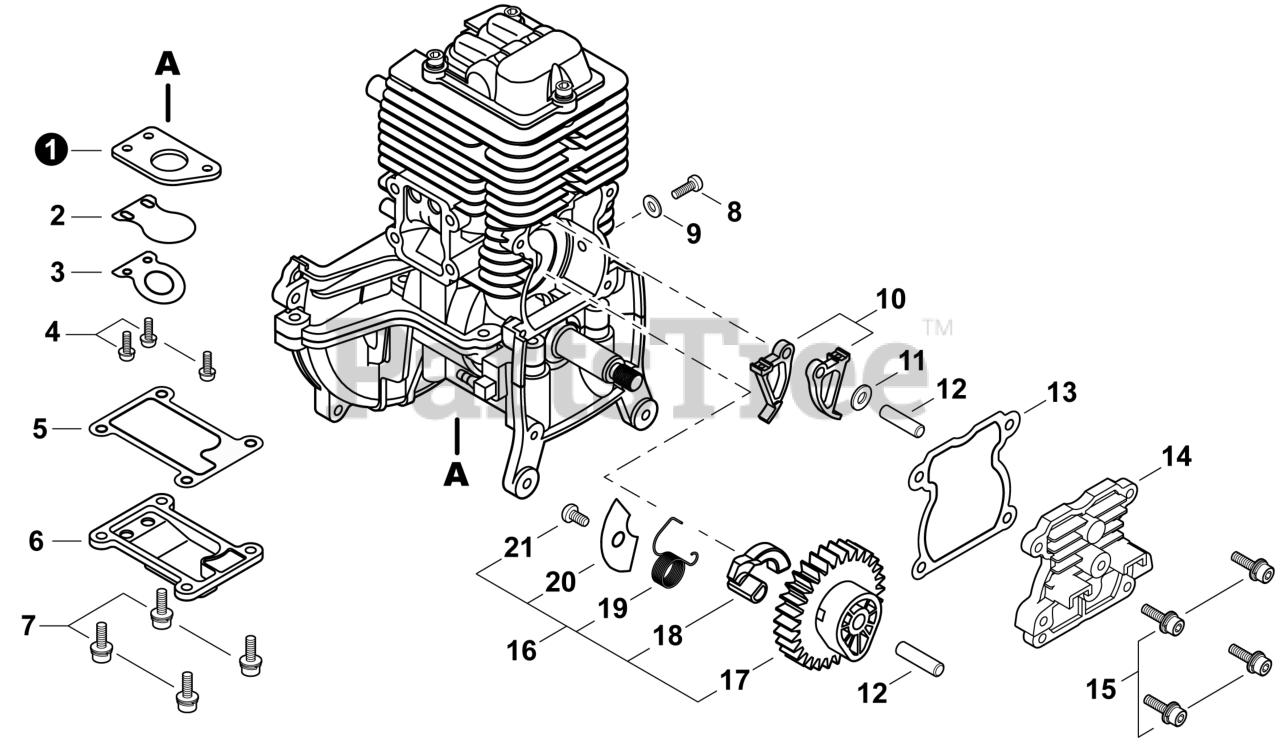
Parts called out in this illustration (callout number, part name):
1	PLATE, REED BACKING
2	VALVE, REED
3	STOP, REED VALVE
4	SCREW M3×10
5	GASKET, REED VALVE
6	COVER, REED VALVE
7	BOLT M4×14
8	SCREW M5
9	WASHER Ø10ר5.5×2
10	FOLLOWER, CAM
11	WASHER 5 MM
12	PIN, LOCATING Ø5×29.8 MM
13	GASKET, CAM GEAR
14	COVER, CAM GEAR
15	BOLT M4×14
16	CAM GEAR ASSY
17	GEAR, CAM
19	SPRING, COIL
20	PLATE, COVER
21	SCREW, TAPPING 4×6
